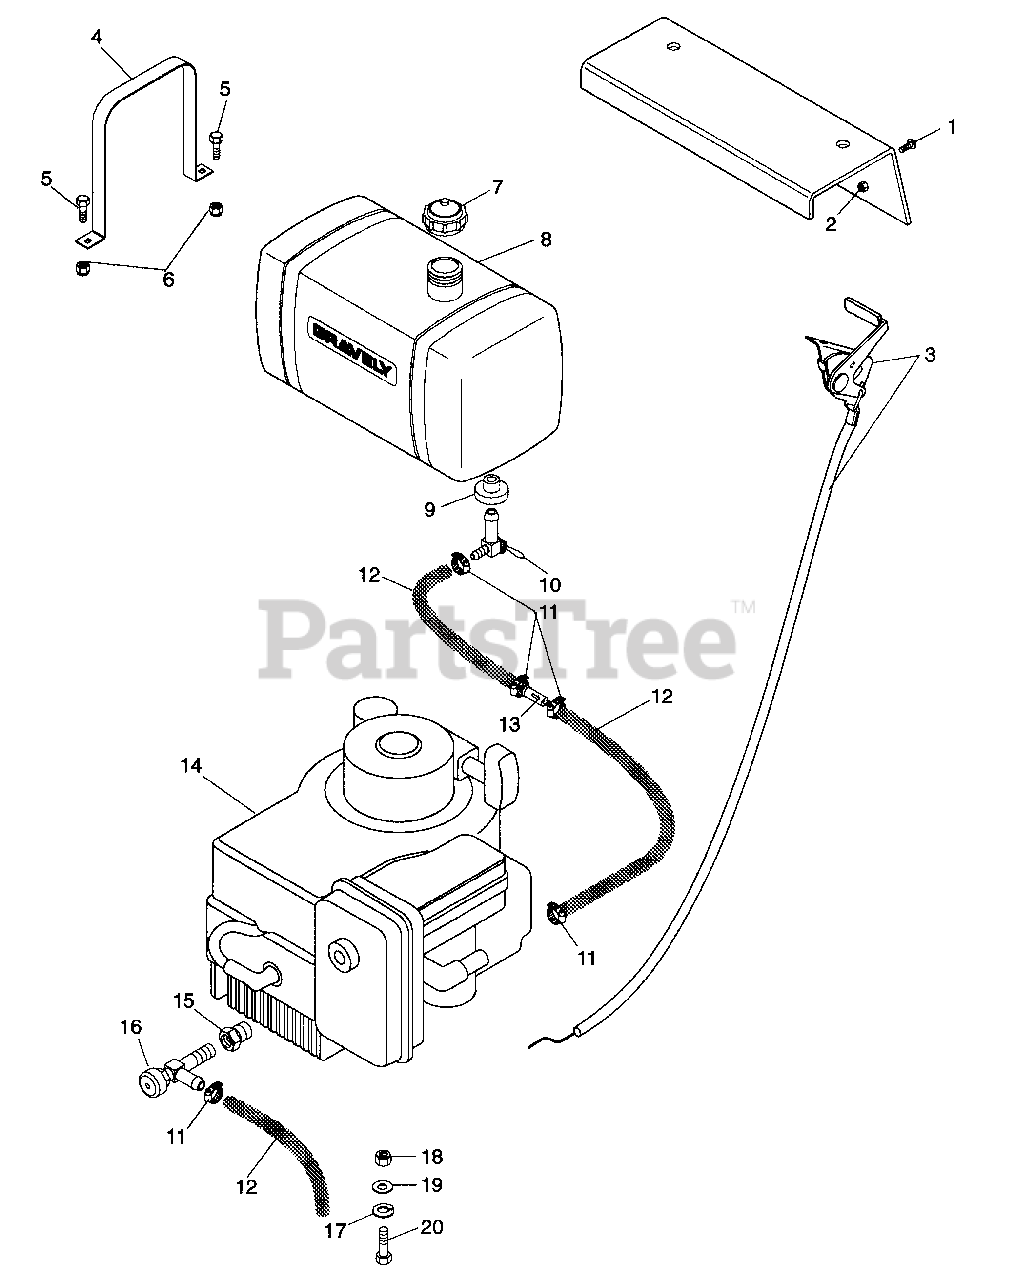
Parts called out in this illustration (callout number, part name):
1	Screw-Machine 10-32 x .50
2	Nut-Locking 10-32
3	Assembly, Throttle Control/Cable
4	Tank Strap for 4.5 G Fuel Tank
5	Bolt-Hex .25-20 x .75 Grade 5
6	Nut-Locking-Nylon .250-20 Grade 2
7	Cap, Fuel Tank
8	Fuel Tank, 4.5 Gallon
9	Bushing, Flange .375 x 1.06 x .625
10	Valve, Ball Shut-Off
11	Hose Clamp
12	Gas Line-Bulk
13	Filter, Fuel
14	Engine, Kawasaki
14	Engine-14 HP Kawasaki
14	Engine, 14 HP Kohler, PS-141
14	Engine, 12.5 HP Command
14	Engine, 15 HP Kohler Command
15	Adapter, Oil Drain
16	Cock, Oil Drain
17	Washer-Lock .313 x .078
18	Nut-Locking-Nylon .312-18 Grade 2
19	Washer-Flat-Steel .344 x .688 x .065
20	Bolt-Hex M8 x 1.25 x 30 MM
